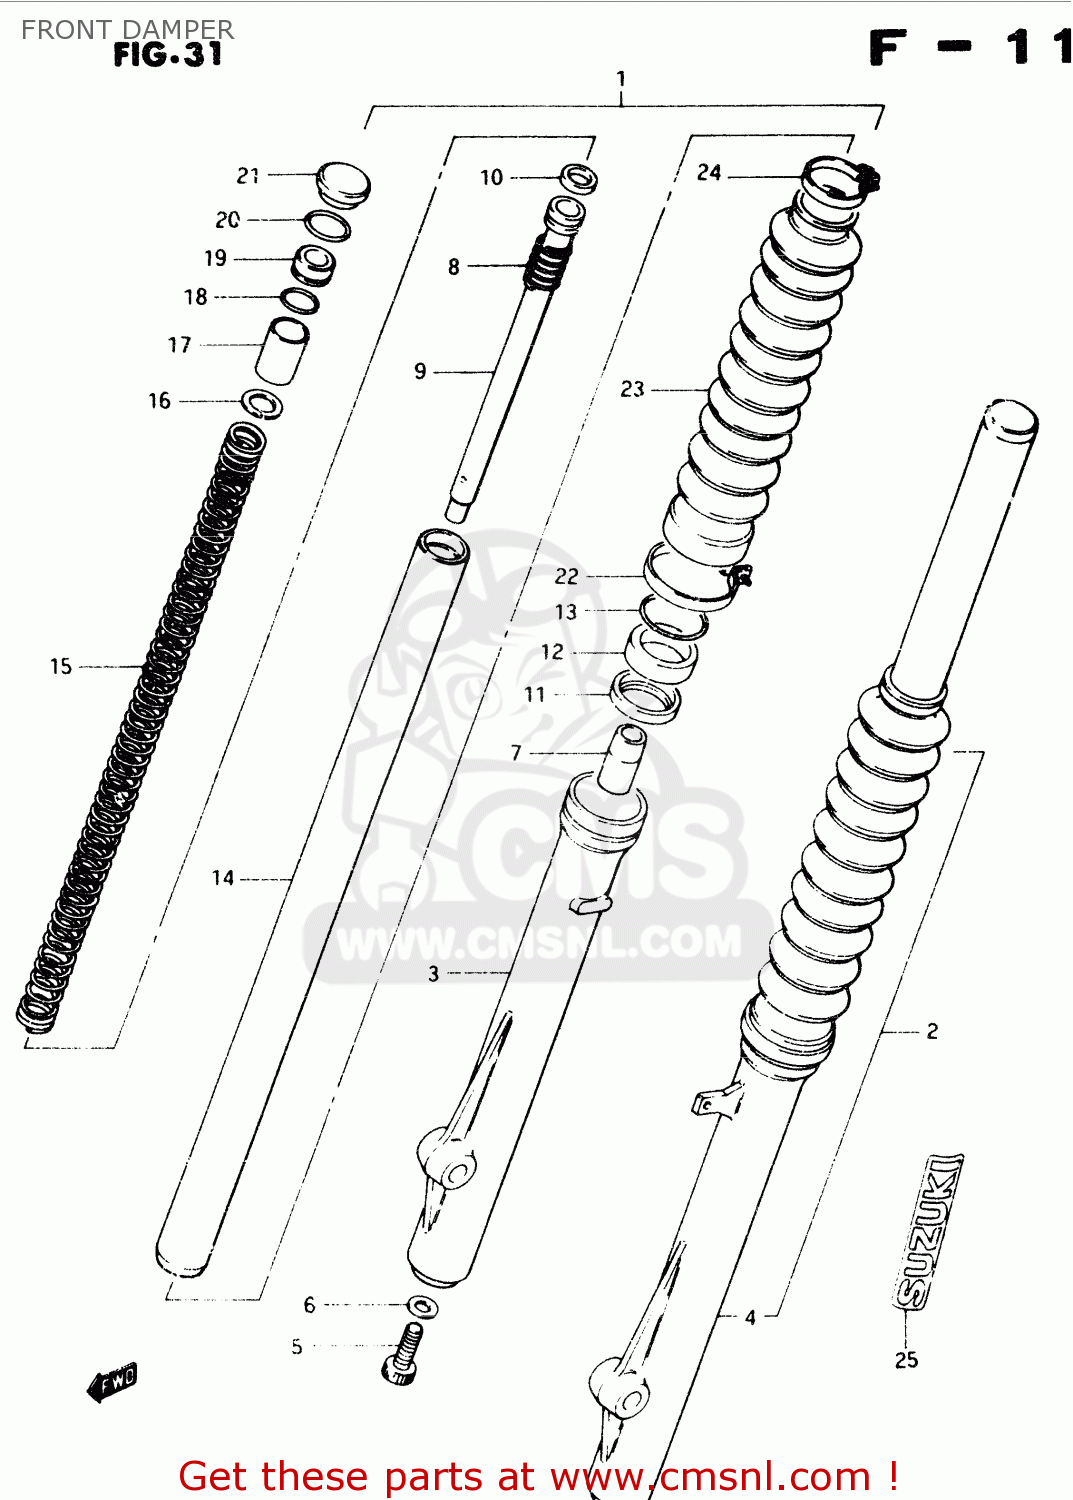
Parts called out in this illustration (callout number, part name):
1	DAMPER ASSY,FR FORK,R
2	DAMPER ASSY,FR FORK,L
3	OUTER TUBE, RH
4	TUBE,OUTER,L
5	BOLT(8X27)
6	GASKET (NAS)
7	PIECE, OIL LOCK
8	SPRING,REBOUND
9	CYLINDER
10	RING,PISTON
11	SPACER
12	SEAL,OIL
13	SEAL,OIL STOPPER RING
14	TUBE,FORK INNER
15	SPRING
16	SEAT,SPRING
17	SPACER
18	O RING
19	SEAT,SPRING
20	RING,STOPPER
21	CAP,FR FORK
22	BAND,FR FORK BOOT
23	BOOT
24	BAND,BOOT
25	EMBLEM (GRAY)
